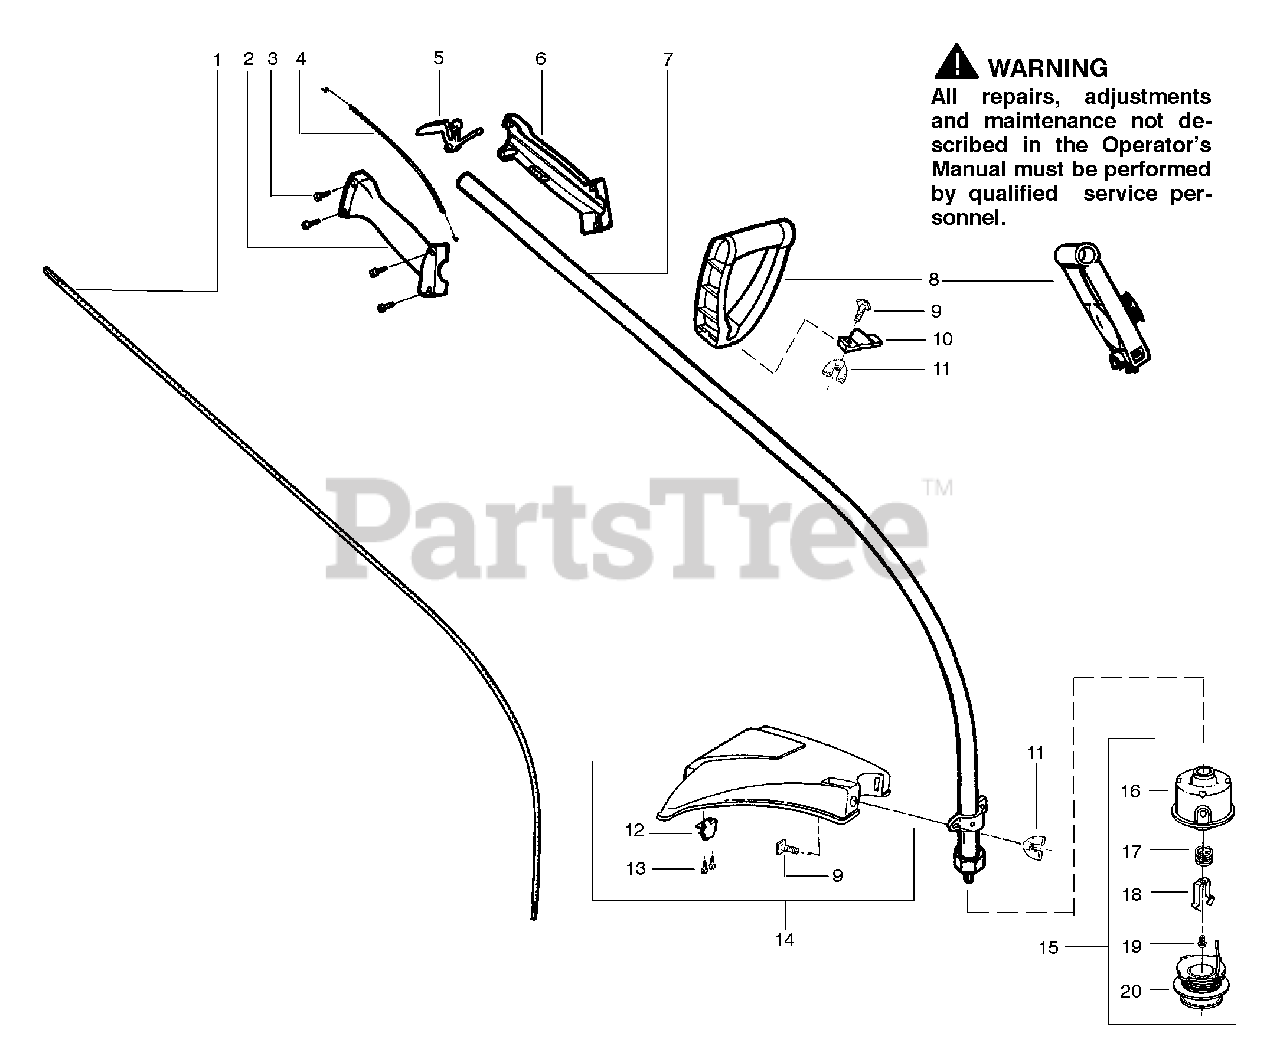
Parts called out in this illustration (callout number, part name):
1	Shaft-Flex Featherlite Plus 50"
1	Shaft-Flex Featherlite Plus 51"
2	Throttle Hsg. (Right)
3	Screw-Throttle Hsg.
4	Kit-Throttle Cable Ass'y.
6	Throttle Hsg. (Left)
7	Drive Shaft Hsg. Ass'y Featherlite Plus 50"(steel tube)
7	Drive Shaft Hsg. Ass'y Featherlite Plus 51"(alum. tube)
8	Assist Handle Featherlite Plus
8	Assist Handle Featherlite Plus (w/spool buddy)
9	Bolt-Handle/Shield
10	Clamp-Handle Assist Featherlite Plus
10	Clamp-Handle Assist Featherlite Plus w/spool buddy
11	Wingnut-Handle/Shield
12	Line Limiter
13	Screw-Line Limiter
14	Kit-Shield Ass'y.
15	Cutting Head Ass'y.
16	Kit-Hub Ass'y
17	Spring-Compression
18	Clip-Retainer-Head
19	Screw w/ Washer-Head
20	Spool w/Line
